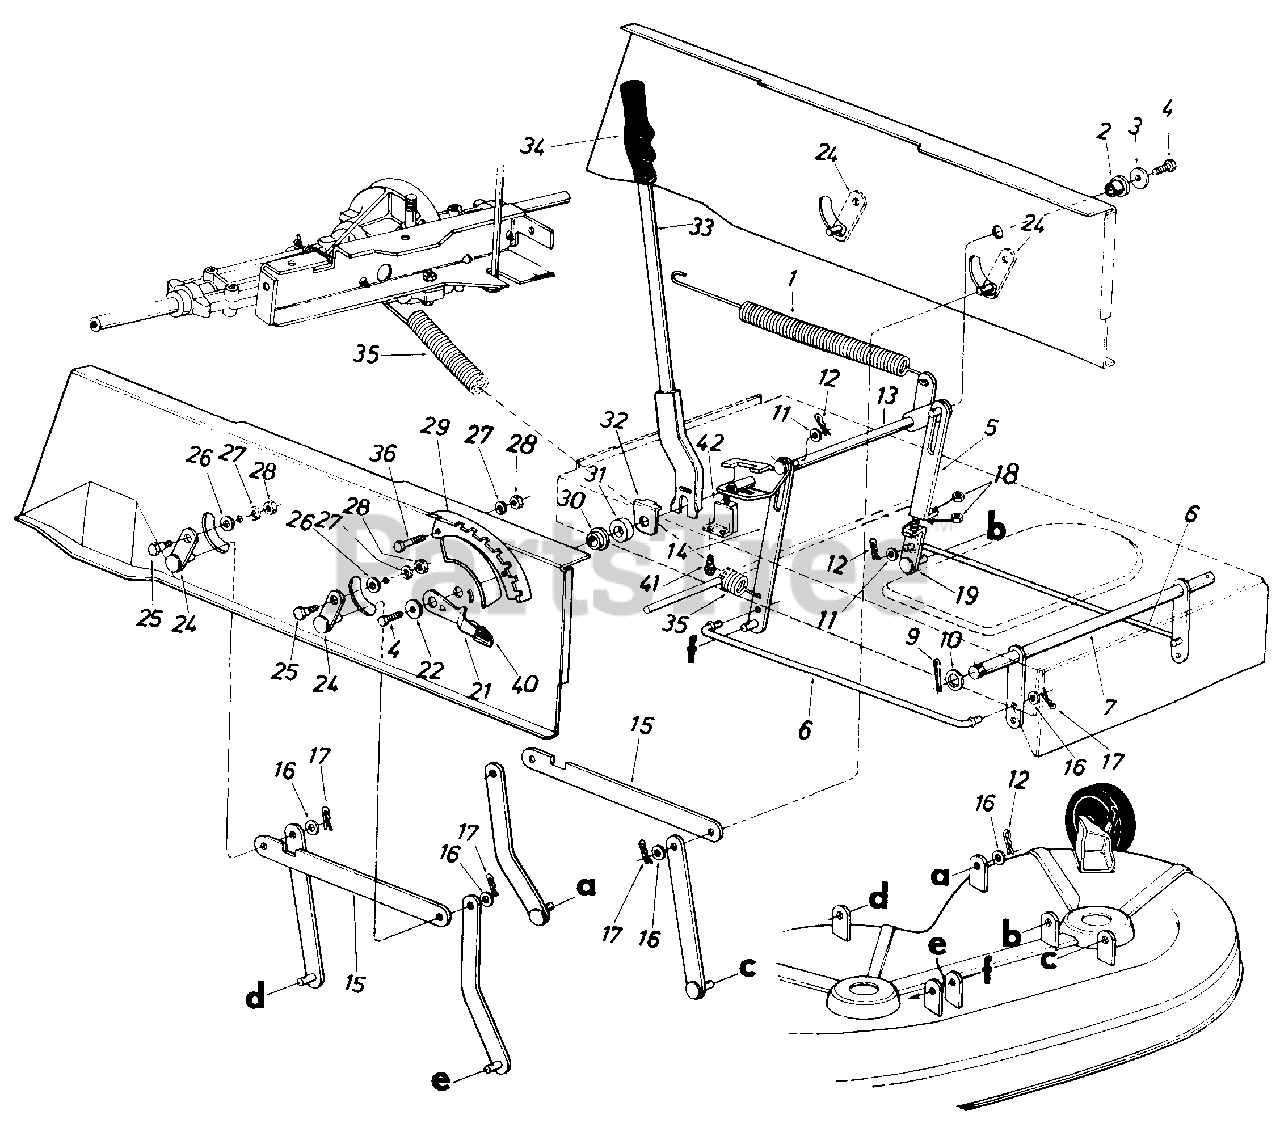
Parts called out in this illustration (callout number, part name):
1	Extension Spring .99" O.D. x 11.00" Lg.
2	Flange Bearing .634" I.D.
3	Fl-Wash. .344" I.D. x 1.125" O.D. x .125
4	Hex Wash. Hd. Scr. 5/16-18 x .62" Lg.
5	Adj. Link Lift
6	Stabilizer Rod
7	Stabilizer Shaft Ass'y.
9	Cotter Pin 118" Dia. x 11/4" Lg.*
10	Fl-Wash. .635" I.D. x 1.12" O.D.
11	Fl-Wash. .531" I.D. x .940" O.D.
12	Inter. Cotter Pin .50" Dia.
15	Connecting Rod
16	Fl-Wash. .40" I.D. x .88" O.D.
17	Inter. Cotter Pin For 3/8 Rod
18	Hex Jam Nut 3/8-16 Thd.
19	Adj. Link Lift Ass'y.
21	Deck Lift Down Stop
22	Fl-Wash. .344" I.D. x 1.125" O.D. x .125
24	Pivot Link Ass'y.
25	Shld. Bolt .437" Dia. x .180" Lg. (5/16-18)
26	Fl-Wash. .344" I.D. x .62" O.D.
27	L-Wash. 5/16" I.D.*
28	Hex Nut 5/16-18 Thd.
29	Index Brk't.
30	Flange Wash. .628" I.D. x 1.25" O.D.
31	Rubber Wash. 1.50" O.D. x .63" I.D. x .60
32	Retainer Washer Lift Handle
33	Lift Handle Ass'y.
34	Grip
35	Extension Spring .99" O.D. x 14.25" Lg.
36	Hex Bolt 5/16-18 x .75" Lg.
40	Knob
41	Hex AB-Tap Scr. #10 x .50" Lg.
42	Safety Switch
